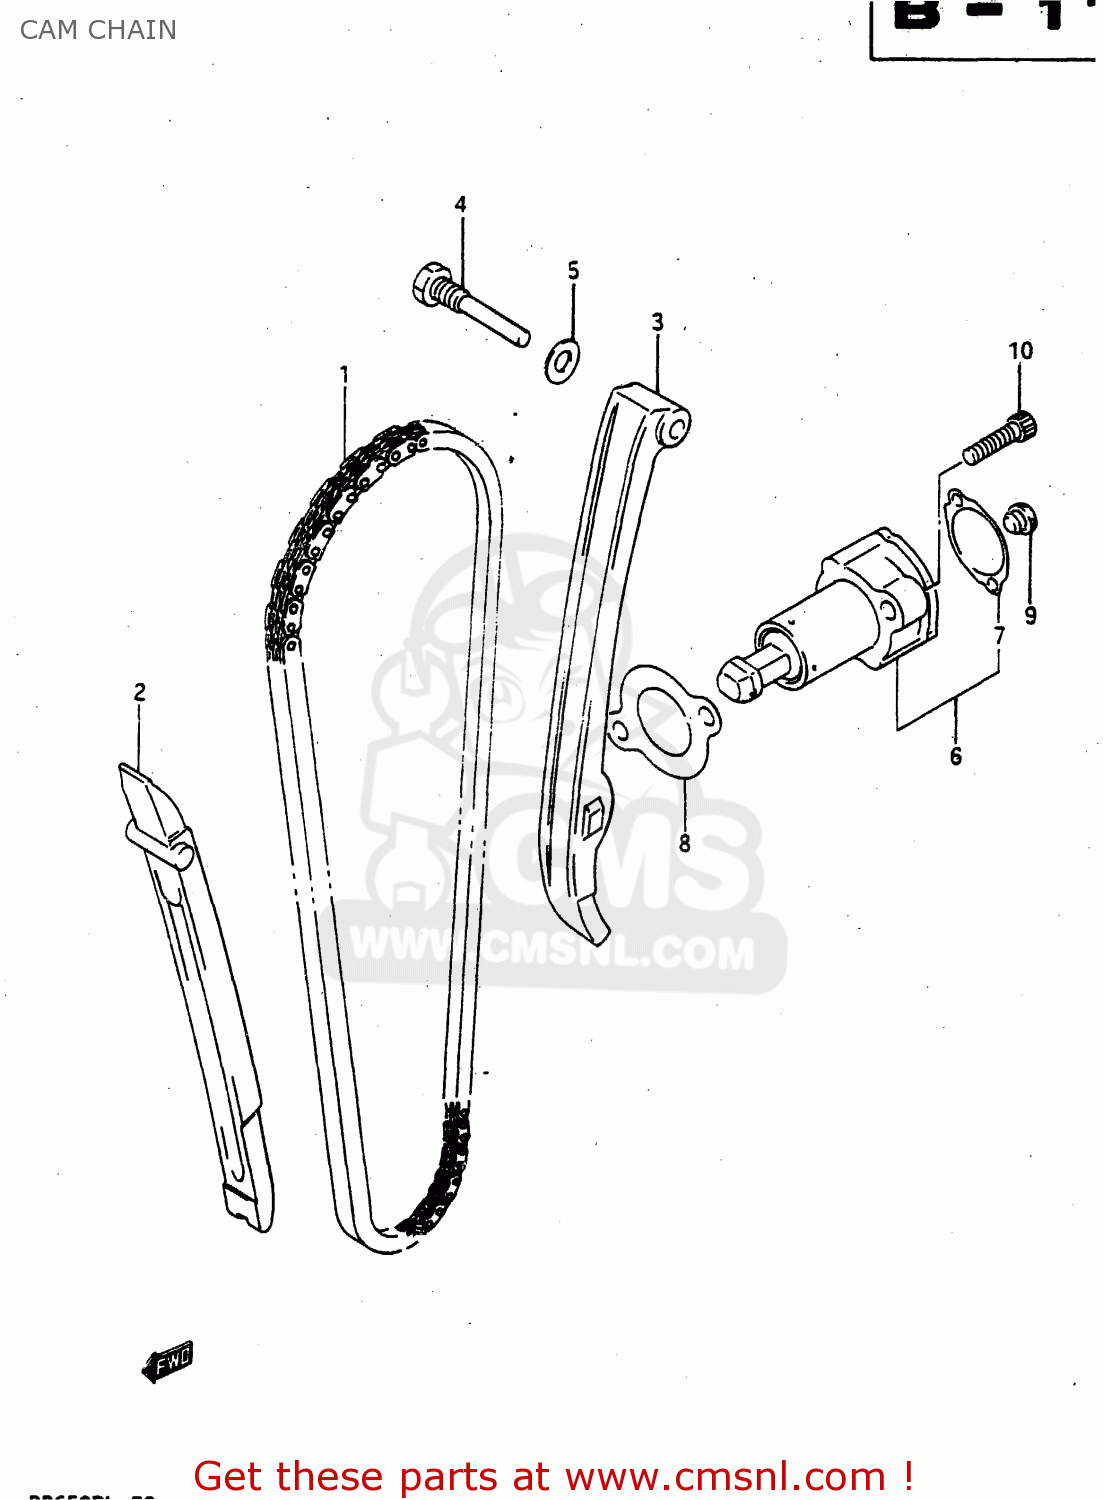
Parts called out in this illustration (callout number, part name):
1	CHAIN,CAMSHAFT DRIVE
2	GUIDE,CAM CHAIN
3	TENSIONER,CAM CHAIN
4	BOLT,CAM CHAIN TENSIONER
5	GASKET 8.2X14X1 (NAS)
6	ADJUSTER ASSEMBLY,TENSIONER
7	GASKET,ADJUSTER CAP (MCA)
8	GASKET,TENSIONER ADJUSTER
9	PLUG,ADJUSTER
10	BOLT
